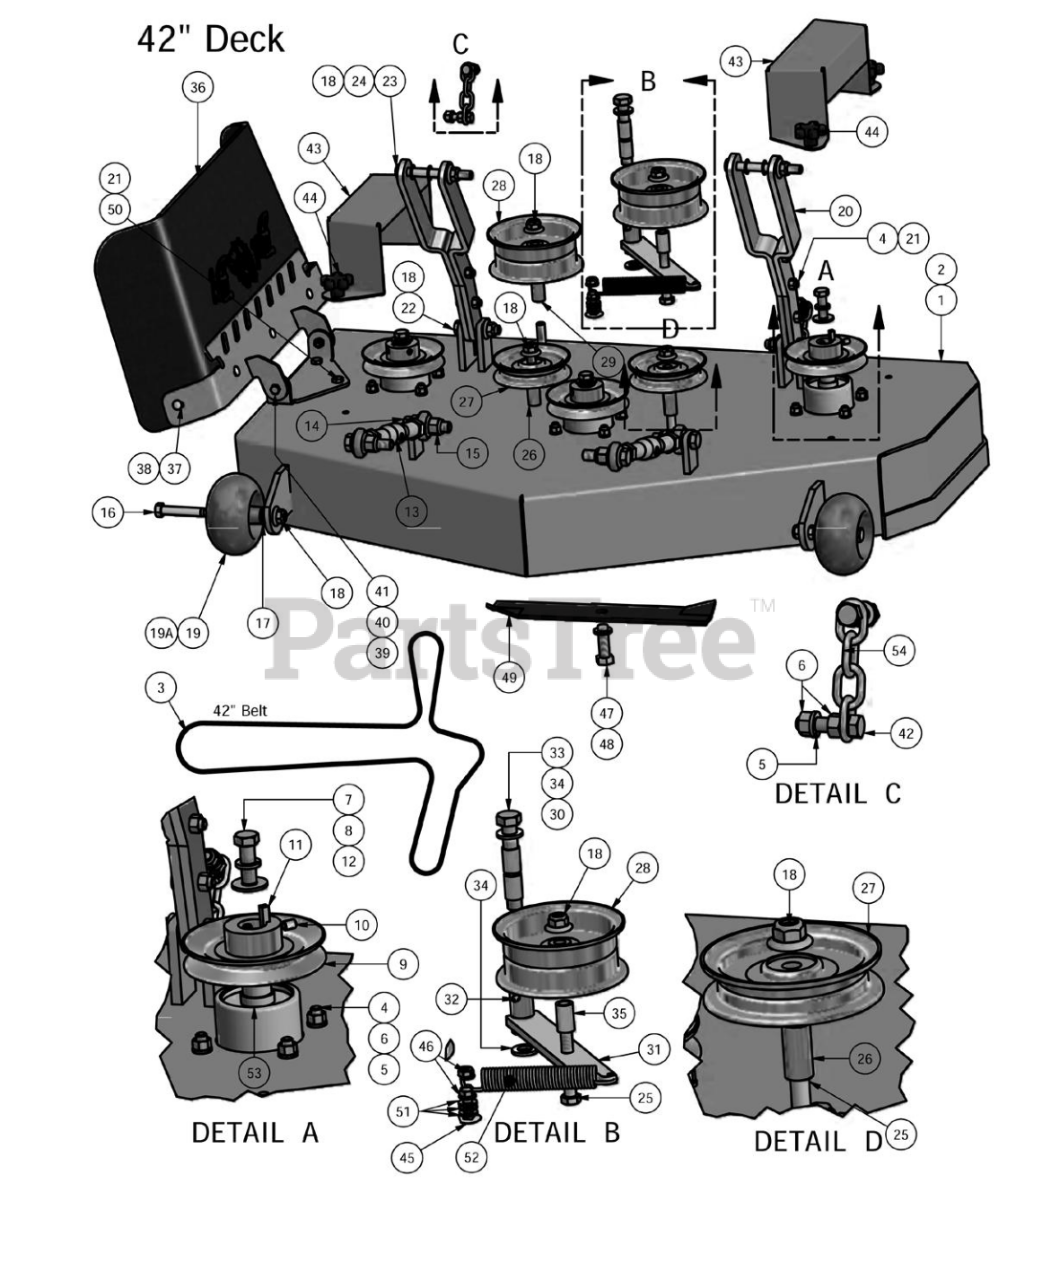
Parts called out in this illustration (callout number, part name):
1	42 Commercial ZT Deck
2	42 Commercial ZT Deck-Complete with Spindles
3	42" Deck Belt-B120
4	3/8" x 1 1/4" Hex Bolt
5	3/8" Lock Washer
6	3/8" Hex Nut
7	1/2" x 1 1/2" Hex Bolt
8	1/2" Lock Washer
9	5" Deck Pulley
10	3/8" Set Screw
11	1/4" x 1" Key
12	5/8" Belleville Washer #K2000-G-150
13	Turnbuckle
14	5/8" x 2 1/2" Hex Bolt
15	5/8 Std NC Nylock Nut
16	1/2" x 4" Bolt (Grade 8)
17	1/2" Flange Nut
18	1/2-13 Nylon Flange Nut-Orange
19	Anti-Scalp Rollers
19A	Deck Wheel Complete Assembly
20	Deck Support Arm
21	3/8" Hex Nut
22	1/2" x 2 1/2" Hex Bolt
23	1/2" x 4 1/2" Bolt
24	1/2" Brass Washer
25	1/2 x 3 1/2 Flange Bolt Grade 8
26	Pup Pulley Spacer
27	4 3/4" Idler Pulley
28	5 3/4" Deck Idler Pulley
29	1 3/4" Pulley Spacer
30	5/8" ID x 1 1/8" Brass Bushing
31	Deck Idler Arm
32	1/4" Drive in Grease Fitting
33	5/8" x 4" Hex Bolt
34	.635 ID Plastic Washer
35	1.25" Pulley Spacer
36	Rubber Side Discharge
37	1/4" x 34" Carriage Bolt
38	1/4-20 Hex Flange Nuts Zinc w/Serrations
39	3/8" Nylock Nut
40	.360 ID Plastic Washer
41	5/16" x 1" Hex Bolt
42	3/8" x 1 1/2" Hex Bolt
43	48" Spindle Cover
44	5/16" Knob
45	3/8 x 1-1/2 Carriage Bolt
46	3/8" Nylock Flange Nut
47	5/8" x 1 1/2" Hex Bolt
48	5/8" Lock Washer
49	42 inch High Lift Fusion Blade
50	3/8" x 3/4" Hex Bolt
51	3/8" Flat Washer
52	Deck Idler Spring
54	Deck Hanger Assembly
